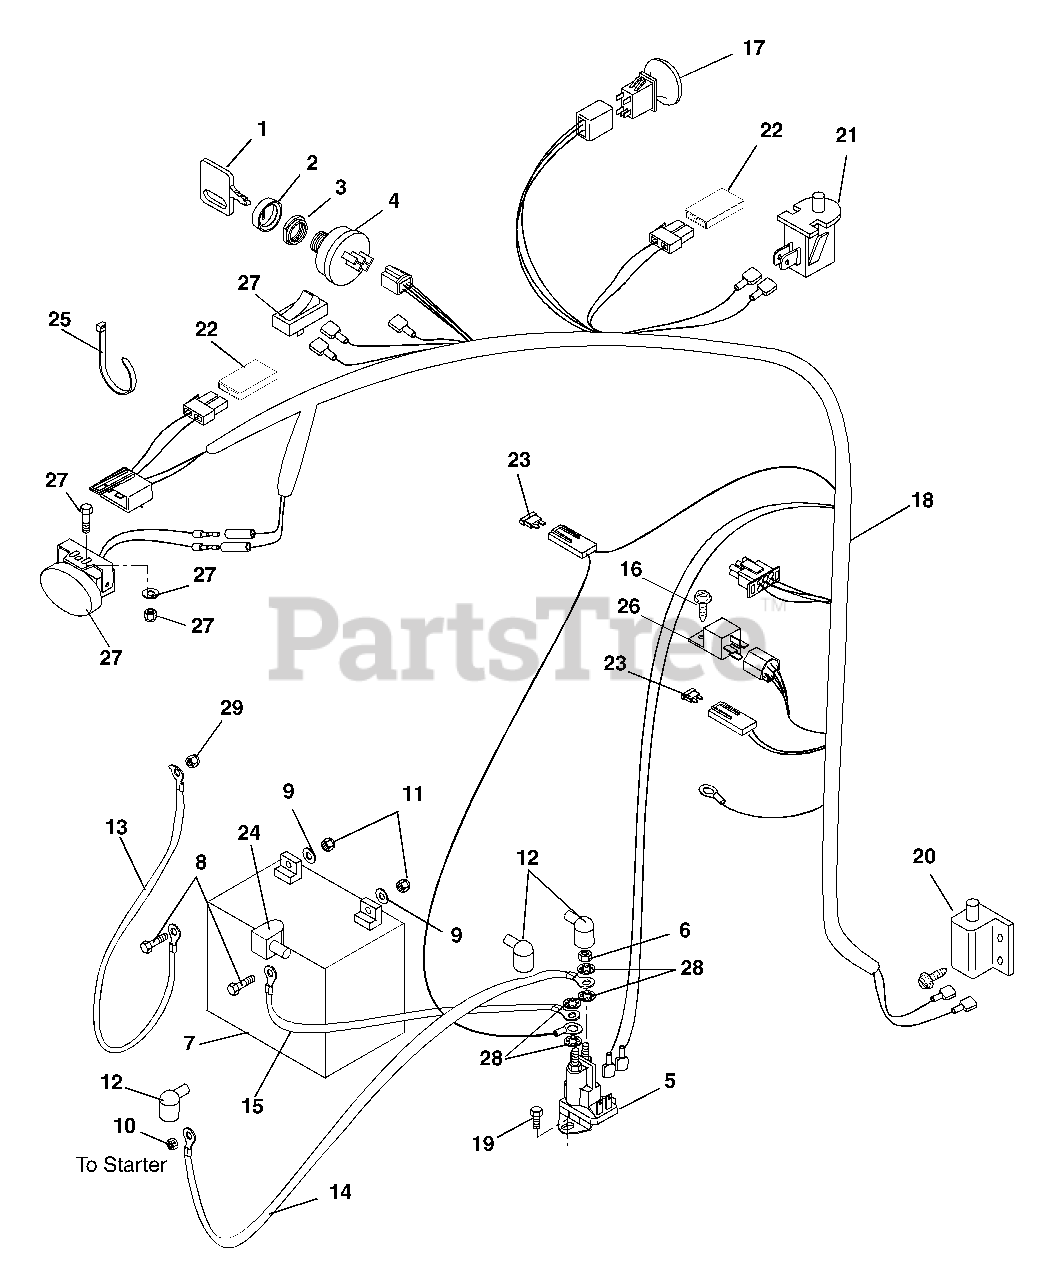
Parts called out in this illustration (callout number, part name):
1	Key, with Cap
2	Cap, Ignition Switch
3	Nut, Panel .625-32
4	Key Switch
5	Solenoid
6	Nut, Jam .31-24
8	Bolt, Hex .25-20 x .75 Grade 5
9	Washer, Locking .25 x .062 Regular
10	Nut, Locking Flange .25-20
11	Nut, Hex .25-20
12	Boot, Eyelet Terminal
13	Cable, Negative Battery
14	Starter Cable 13"
15	Starter Cable 16"
16	Screw, Tapping 10-24 x .375 Pan Head
17	Switch, Clutch With Retainer
18	Harness, Zoom Sport 6 Pin
19	Screw, Tapping .25-20 x .37 Hex Washer Head
20	Switch, Single Pole (N.O.)
21	Switch, Snap Mounting (N.O.)
22	Diode, Connector Shell
23	Fuse-25 AMP
24	Insulator
25	Cable Tie
26	Relay
27	Light Kit
28	Washer, Locking .31
29	Nut, Locking Top Flange .31-18
